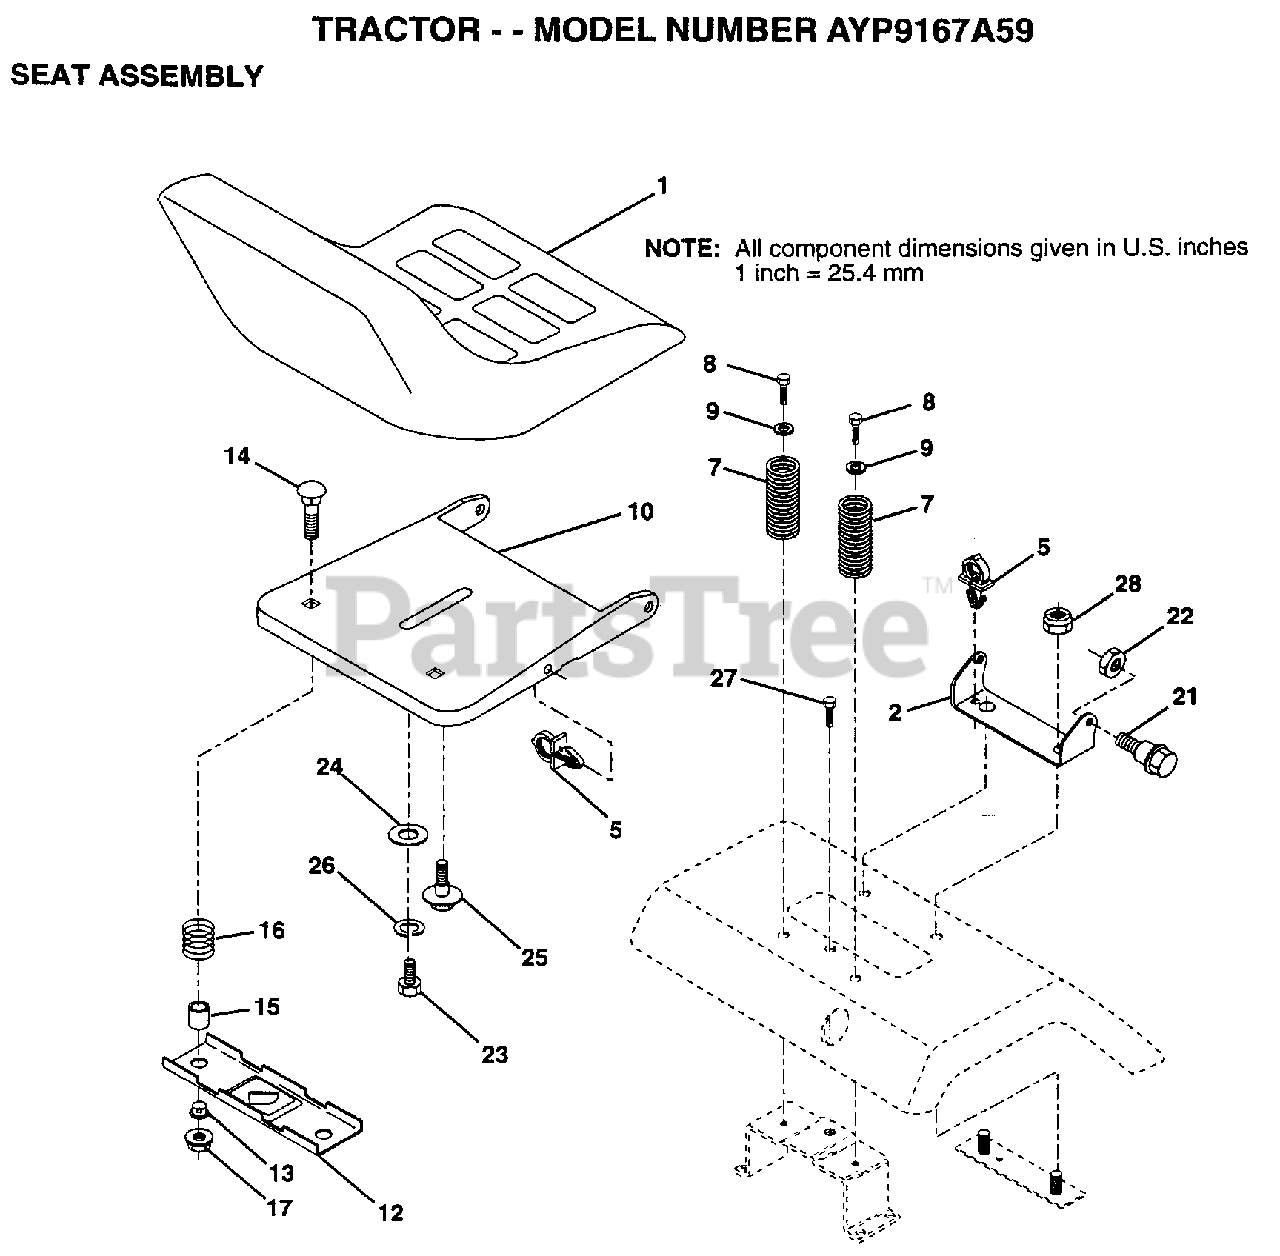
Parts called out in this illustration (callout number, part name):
2	BRACKET PVT SEAT
5	CLIP.PUSH-IN.HING
7	SPRING COMPRESSIO
8	SCREW LT
9	WASHER
12	BRKT SWITCH
13	BUSHING
15	SPLIT SPACER
16	SPRING
21	BOLT.SHLD.5/16-18
22	NUT
23	BOLT
24	WASHER
25	"BOLT,SHOULDER"
26	LOCKWASHER
27	SCREW LT
